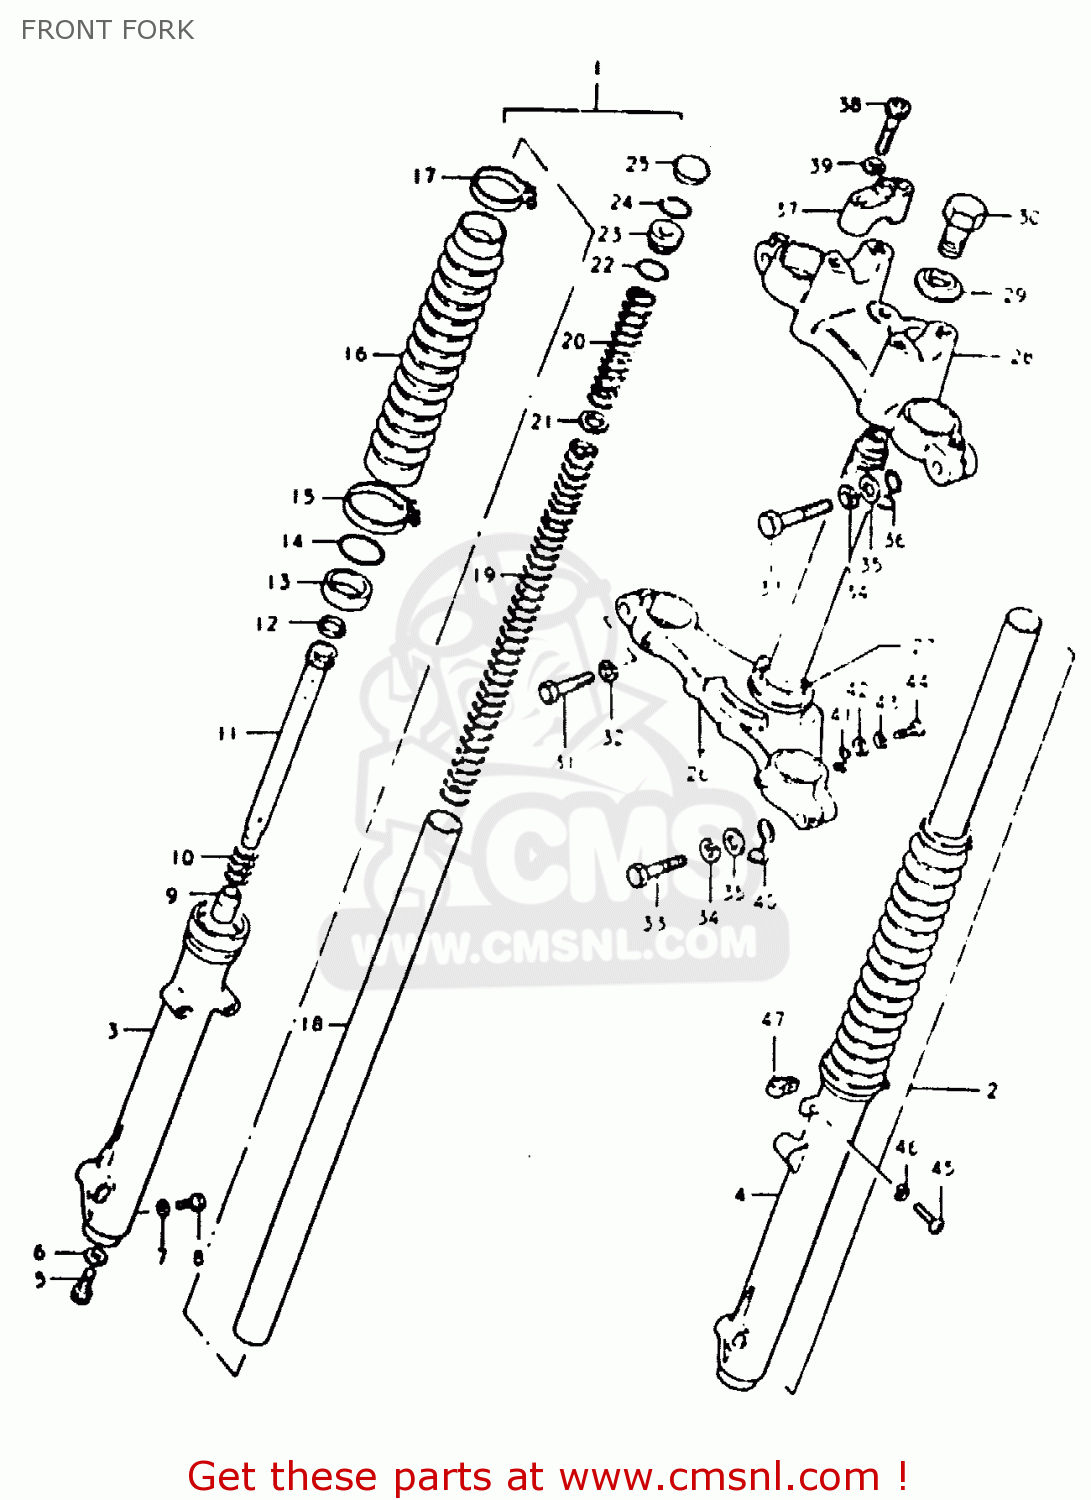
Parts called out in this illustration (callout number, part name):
1	DAMPER ASSY RH
2	DAMPER ASSY LH
3	OUTER TUBE RH
4	OUTER TUBE LH
5	BOLT(8X27)
6	GASKET (NAS)
7	GASKET,DRAIN,PLUG (NAS)
8	BOLT(6X8)
9	PIECE,OIL LOCK
10	SPRING,FORK REBOUND
11	CYLINDER,FRONT FORK
12	RING
13	SEAL,OIL
14	CIRCLIP,FORK OIL SEAL
15	CLAMP
16	BOOT
17	BAND,FRONT FORK COVER BOOT
18	INNER TUBE
19	SPRING A
20	SPRING B
21	SEAT,SPRING
22	O RING
23	SEAT,SPRING
24	RING,STOPPER
25	CAP,FRONT FORK
26	STEM, STEERING (BLACK)
27	RACE,STEERING OUTER LWR
28	HEAD, STEERING STEM
29	WASHER(10.5X30X2.3)
30	BOLT
31	BOLT,M10X1.25X
32	LOCK WASHER
33	BOLT
34	LOCK WASHER
35	WASHER
36	CLIP
37	HOLDER,HANDLEBAR
38	BOLT 8X35
39	LOCK WASHER
40	CLIP
41	CLIP
42	WASHER
43	LOCK WASHER
44	SCREW 6X12
45	SCREW
46	LOCK WASHER
47	CLIP,FR BRAKE CABLE
